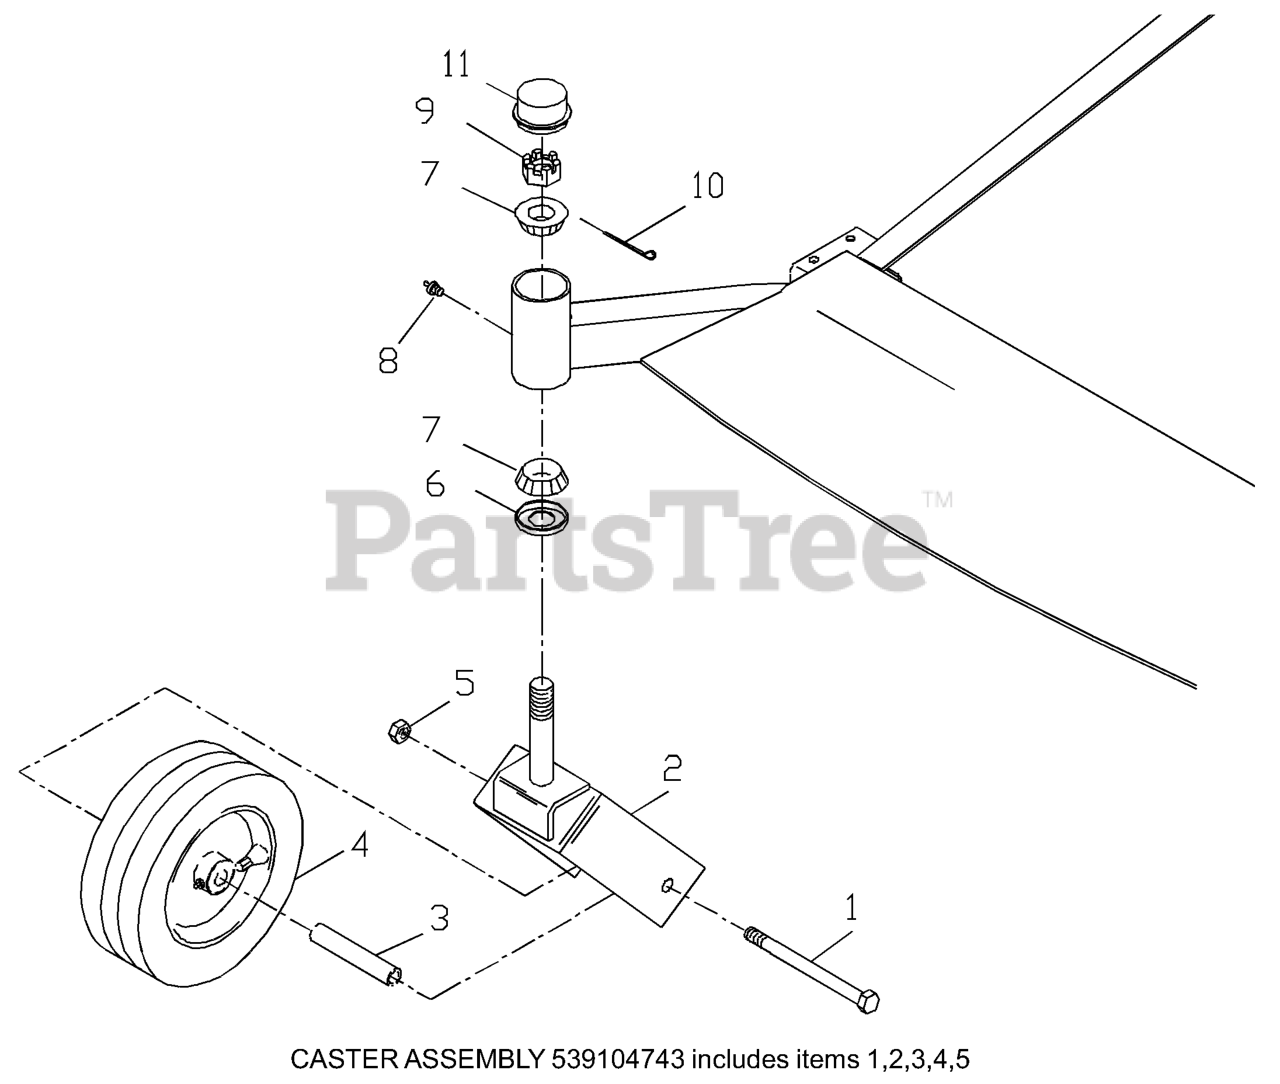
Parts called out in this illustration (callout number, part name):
1	SCREW 1/2C X 7 1/2 HEX CAP
2	CASTER YOKE ORANGE
3	SPACER, CASTER
4	TIRE.ASSEM.13X5-6.SMOOTH.SILVE
4	TIRE - FRONT
4	RIM
4	ROLLER BEARING
4	BEARING RETAINER
4	VALVE STEM TR-412
5	NUT 1/2-13 HEX NYLOC ZD
7	BEARING W/CUP
8	ZERK
9	COTTER PIN 1/8 X 2
10	NUT 1"C HEX SLOTTED
11	GREASE CAP
539104743	CASTER ASM
